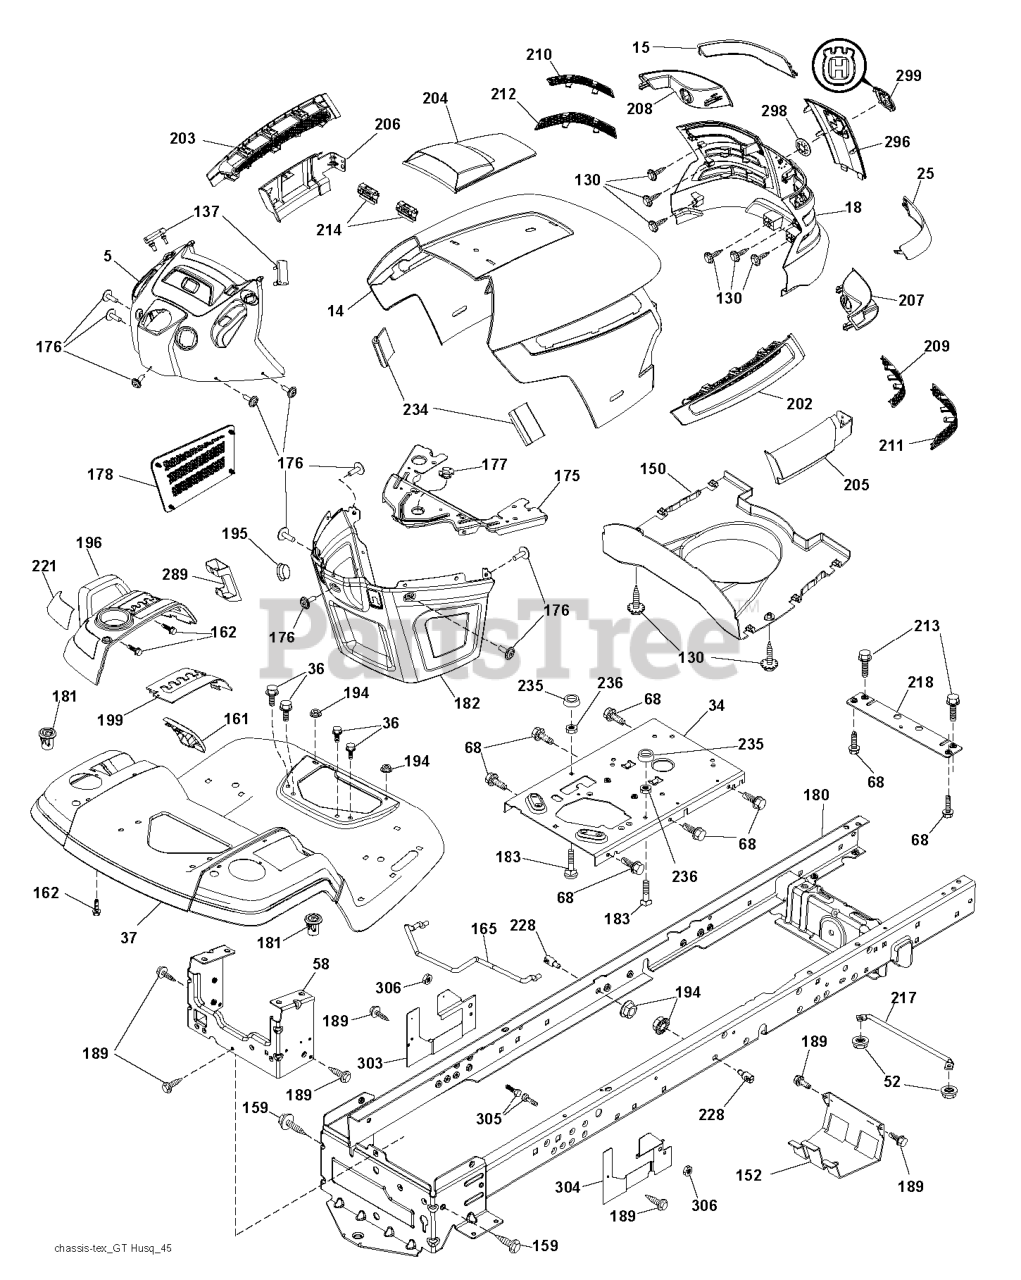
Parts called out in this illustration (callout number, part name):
5	DASH.ASM.HUSQ.GT.E.RECT.W/CK
14	HOOD
15	LENS.LH.TEX.GT.HUSQ.CL
18	GRILL.ASM.HUSQ.TG/CRD.W/TRIM
25	LENS.RH.TEX.GT.HUSQ.CL
34	PLATE.ENGINE.WELDED.CHASSIS
36	SCREW 5/16"
37	FENDER.PNT.TX.GT.CH/FW.ORANGE
52	LOCKNUT
58	DRAWBAR.UPPER.2PC,LRG.FENDER
68	Screw 5/16-18 x 1/2 Hex, Self Tapping 5/16-18 x 1/2
130	SCREW.#10 X 0.750.BOS
137	BUMPER DASH
150	AIR.DUCT.TEXGT.HUSQ.31
152	SHIELD.BROWNING.W/TEX
159	SCREW, 3/8-16X3/4
161	CONSOLE.FUEL.WINDOW.HU
162	SCREW.HI-LO.CONSOLE
165	SUPPORT.TANK.REAR.W/TEX
175	PLATE.CROSSMEMBER.HUSQ
176	SCREW.#10-24X5/8.RN.QU
177	BUSHING, STEERING
178	CARGO.ASM.NET.TXGT.W/C
180	CHASS.WLDMNT.TLT.12GA/2PC.20"
181	BUSHING.MNT.FEND.CRGO.
182	DASH.LOWER.COMMON.12V.ADAPTOR
183	BOLT.5/16-18X1-1/4 FULL.THREAD
189	SCREW
194	NUT LOCK HEX FLANGE 5/16-18
195	PLUG.HOLE.DASH.LOWER.12V.BLK
196	RP CONSOLE.ASM.DECKLFT.W/
199	PLATE.DECK.LIFT.HUSQVARNA.GT
202	VENT.SIDE.HOOD.HUSQ.RH.GREY
203	VENT.SIDE.HOOD.HUSQ.LH.GRAY
204	VENT.ASM.TORPHD.HUSQGT.LOGO.CL
205	SKIRT.HOOD.SIDE.HUSQ.RH.GREY
206	SKIRT.HOOD.SIDE.HUSQ.LH.GREY
207	BEZEL.RH.TEX.GT.HUSQ
208	BEZEL.LH.TEX.GT.HUSQ
209	INSERT.HEX.GRILL.HUSQ.GREY
210	INSERT.HEX.GRILL.HUSQ.
211	INSERT.HEX.GRILL.HUSQ.
212	INSERT.HEX.GRILL.HUSQ.
213	BOLT
214	CLIP.RETAINER.TINNER.
217	ROD.PIVOT.HOOD
218	X-PIECE.HOOD.STOP.NON/
221	REFLECTOR.LH.TEX GT HU
234	BUMPER.HOOD.TEX.HUSQVARNA
235	SPACER FENDER
236	NUT.CENTERLOCK.5/16-
289	PLUG.N/CRUISE.COMMON.YT/GT.BLK
296	TRIM.HUSQ.TG/CRD.SERVICE
298	NUT PUSH M
299	RP LOGO
303	SHIELD CHASSIS LEFT
304	SHIELD CHASSIS RIGHT
306	NUT LOCK FLG 3/8-16 UNC
